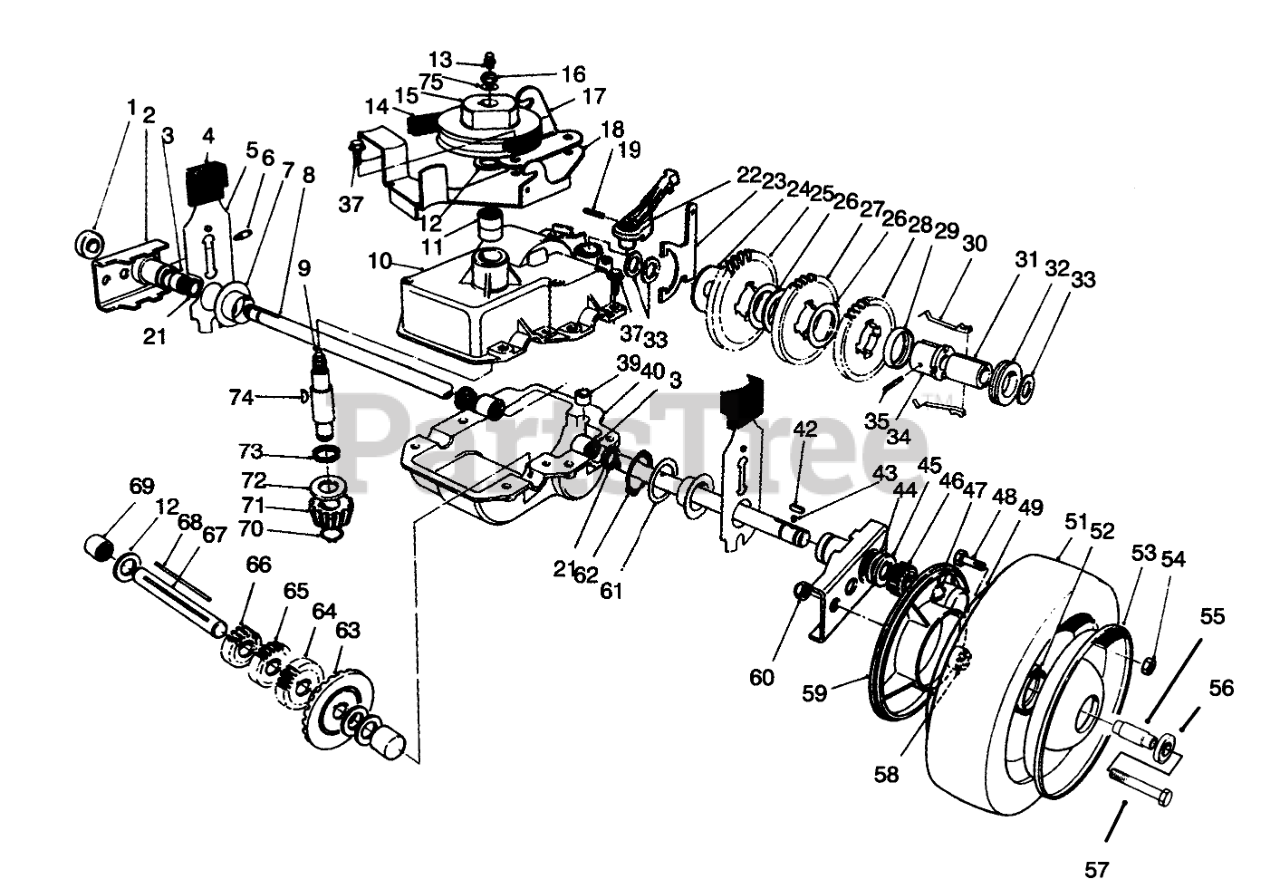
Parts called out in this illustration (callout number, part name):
1	BEARING-WHEEL
2	Pivot Arm Assembly (Incl. Ref. #1,3,6&21)
3	BEARING-ROLLER
4	KNOB-ARM
5	REAR SPRING ARM ASM
7	CAP-END
8	SHAFT-OUTPUT
9	Shaft-Input (Incl Ref. #13)
10	Upper Case Assembly (Incl. Ref. #11&73)
11	BEARING-NEEDLE
12	WASHER-THRUST
13	FITTING-GREASE, ZERK
14	V-BELT
15	PULLEY
16	NUT-HEX
17	Bracket-Traction Engage
18	Belt Guide Bracket
19	PIN-COIL
21	SEAL-OIL
22	LEVER-SHIFT
23	YOKE-SHIFT
24	WASHER
26	WASHER
27	GEAR-42T
28	GEAR-38T
29	RETAINER-KEY
30	KEY-SHIFT
31	SLEEVE
32	COLLAR-SHIFT
33	WASHER-PLAIN
34	SLEEVE-GEAR
35	PIN-GROOVE
37	SCREW-HWHTF
39	BUSHING-YOKE
40	CASE-GEAR, LOWER
43	SPRING-COMPRESSION
44	WASHER-THRUST, OUTER
45	WASHER-THRUST, OUTER
46	GEAR-PINION
47	RING-RETAINING
48	SCREW-HH
49	Wheel-Half
52	HUB-BEARING
53	Wheel-Half
54	NUT-LOCK, NI
55	SPACER-BEARING
56	BEARING-WHEEL
57	SCREW-HH
58	SPACER-COVER, WHEEL
59	COVER-WHEEL
60	NUT-LOCK, CONE
61	WASHER
62	RING-RETAINING
63	GEAR-BEVEL
64	GEAR-18T
65	GEAR-14T
66	GEAR-12T
67	SHAFT-INTERMEDIATE
69	BEARING-NEEDLE, CLOSED
70	RING-RETAINING
71	PINION-BEVEL
72	WASHER-THRUST
74	KEY-WOODRUFF
75	WASHER-FLAT
